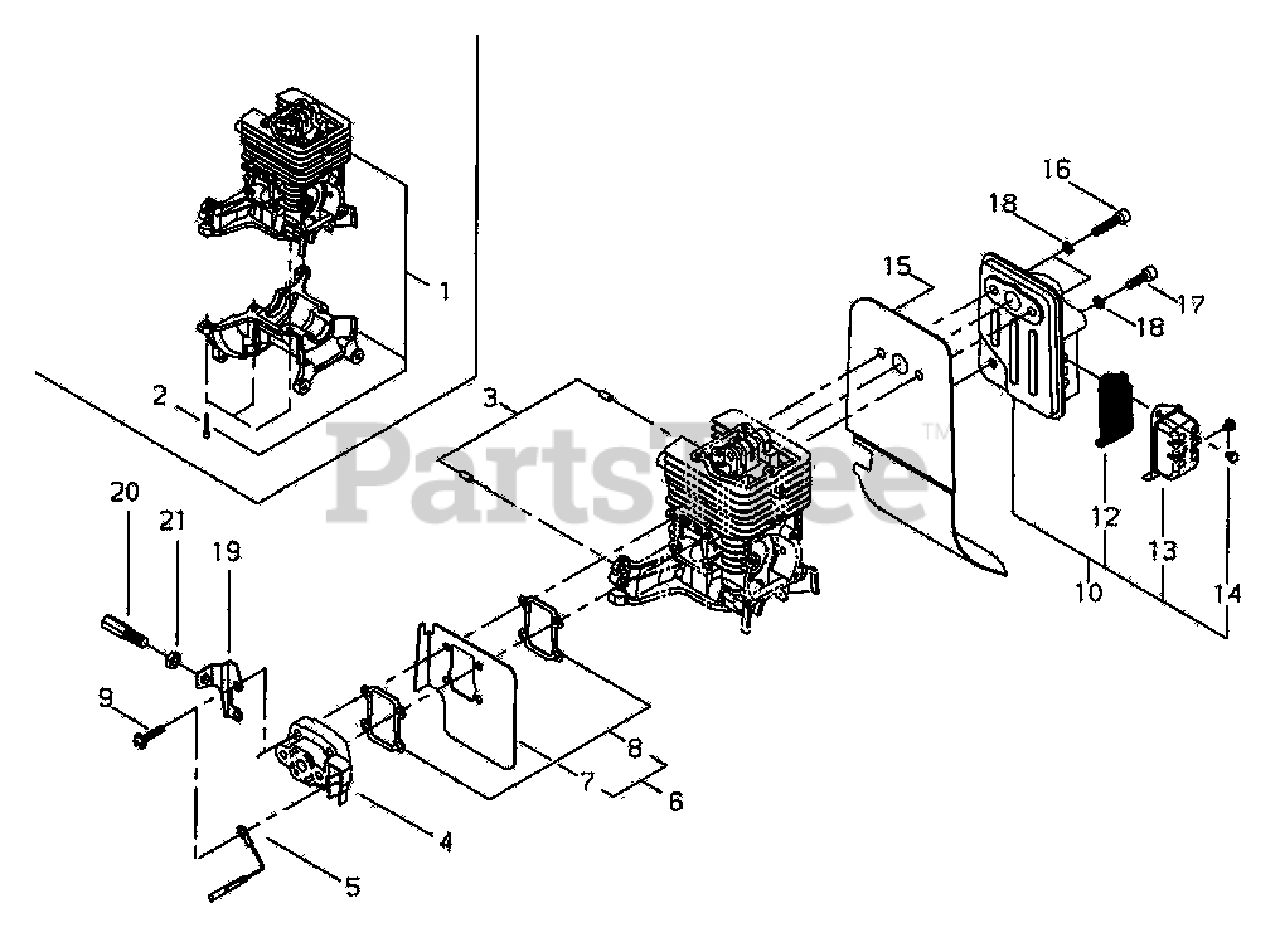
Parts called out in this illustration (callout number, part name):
1	CYLINDER BLOCK SET
2	SCREW - 5X16
3	PIN - LOCATING
4	INSULATOR
5	LEAD - GROUND
6	HEAT DEFLECTOR ASSY
7	DEFLECTOR, HEAT
8	SHIELD, INTAKE
9	SCREW - 5X22
10	MUFFLER ASSY
12	SCREEN, SPARK ARRESTOR
13	GUIDE, EXHAUST
14	SCREW - 4X6
15	SHIELD, EXHAUST
16	SCREW - 5X25
17	SCREW - 5X16
18	WASHER - 5
19	BRACKET, THROTTLE CABLE
20	NUT, CABLE ADJUST
21	LOCKNUT - 6
